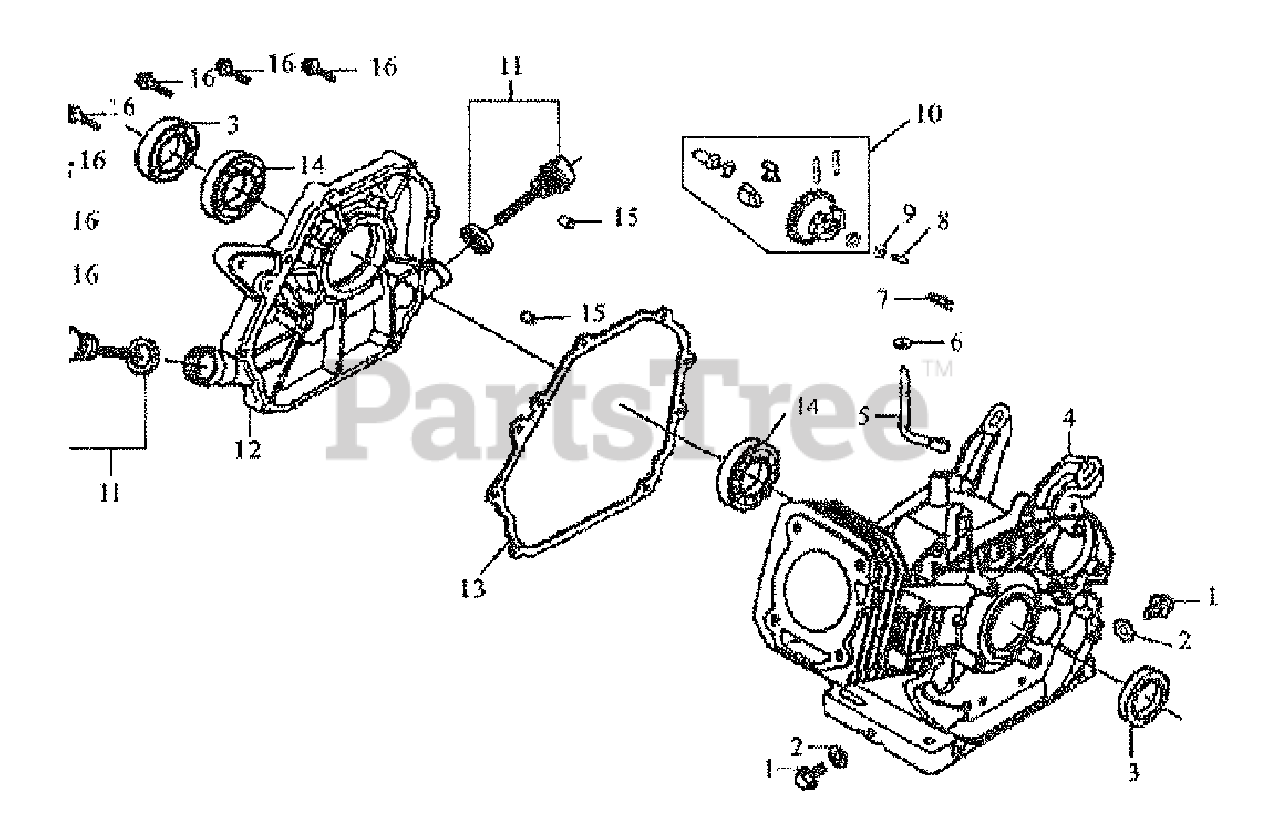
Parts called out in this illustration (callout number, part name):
1	PLUG. DRAIN
2	WASHER. DRAIN PLUG
3	SEAL. OIL. CRANKSHAFT
4	CRANKCASE
5	BAR. SWAY. REGULATING
7	PIN. SPLIT
8	SHAFT. REGULATING
9	RING. SNAP
10	GEAR ASSY. DRIVE
11	DIPSTICK.(WITH GASKET)
12	COVER. CRANKCASE
13	GASKET. CRANKCASE
14	BEARING(6205)
15	PIN. SET. M8X14
16	BOLT. M8X33.5
